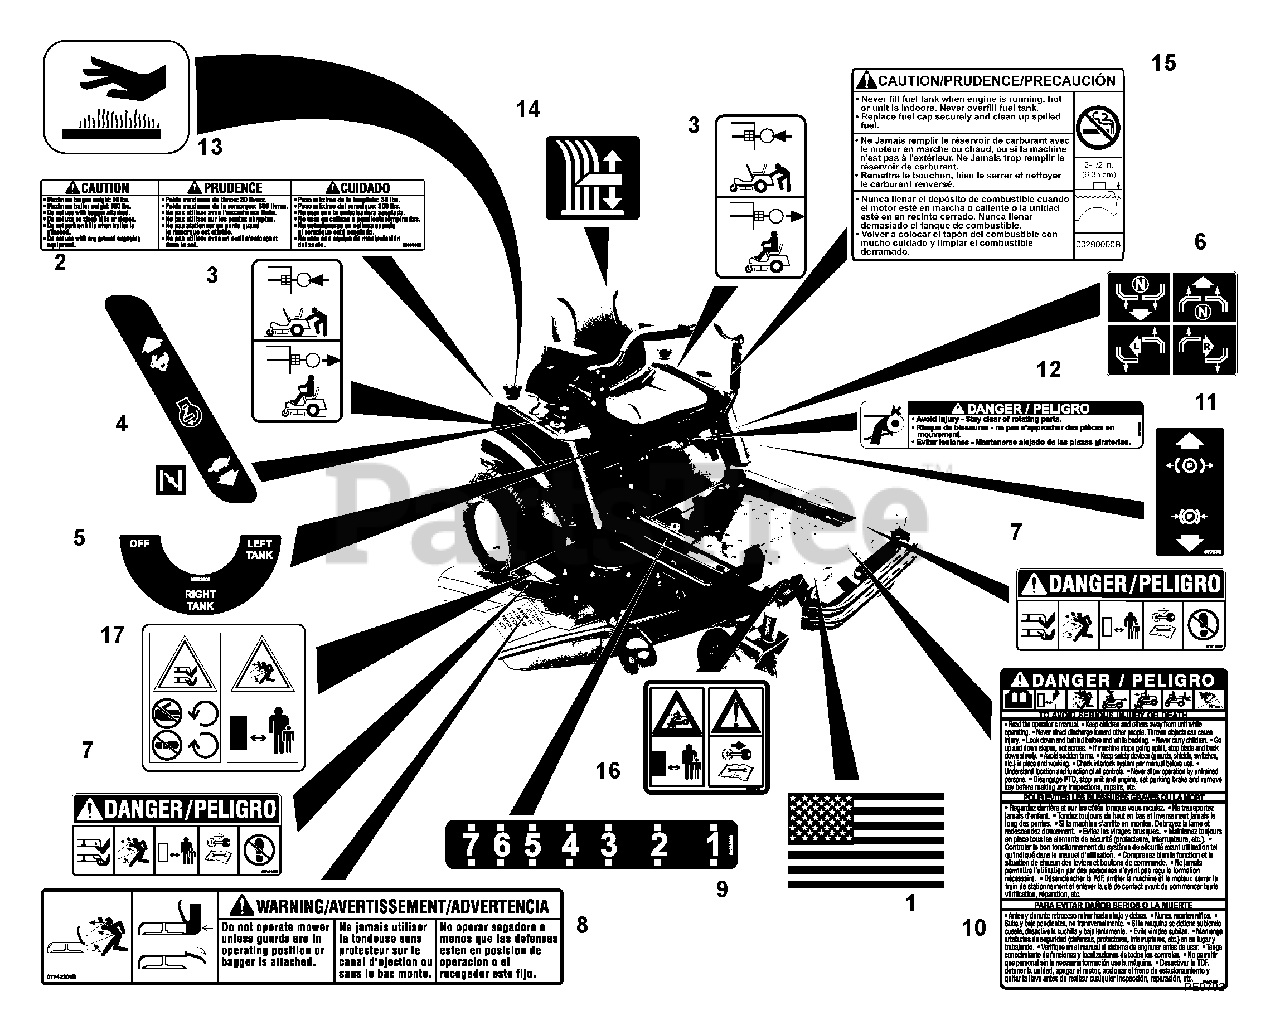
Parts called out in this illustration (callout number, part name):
1	DECAL, AMERICAN FLAG
2	DECAL, TRAILER HITCH
3	DECAL, TRANSMISSION DISCONNECT
4	DECAL, SPEED CONTROL
5	DECAL, FUEL VALVE
6	DECAL, INSTRUCTIONAL-STEERING
7	DECAL, MOWER PAN DANGER
8	DECAL, WARNING
9	DECAL CUT HEIGHT
10	DECAL, DANGER BILINGUAL
11	DECAL, PARKING BRAKE LEVER
12	DECAL- DANGER
13	DECAL, HOT SURFACE
14	DECAL-CUT HEIGHT
15	DECAL,FUEL WARNING
16	DECAL, CE CAUTION
17	DECAL, CE DECK
